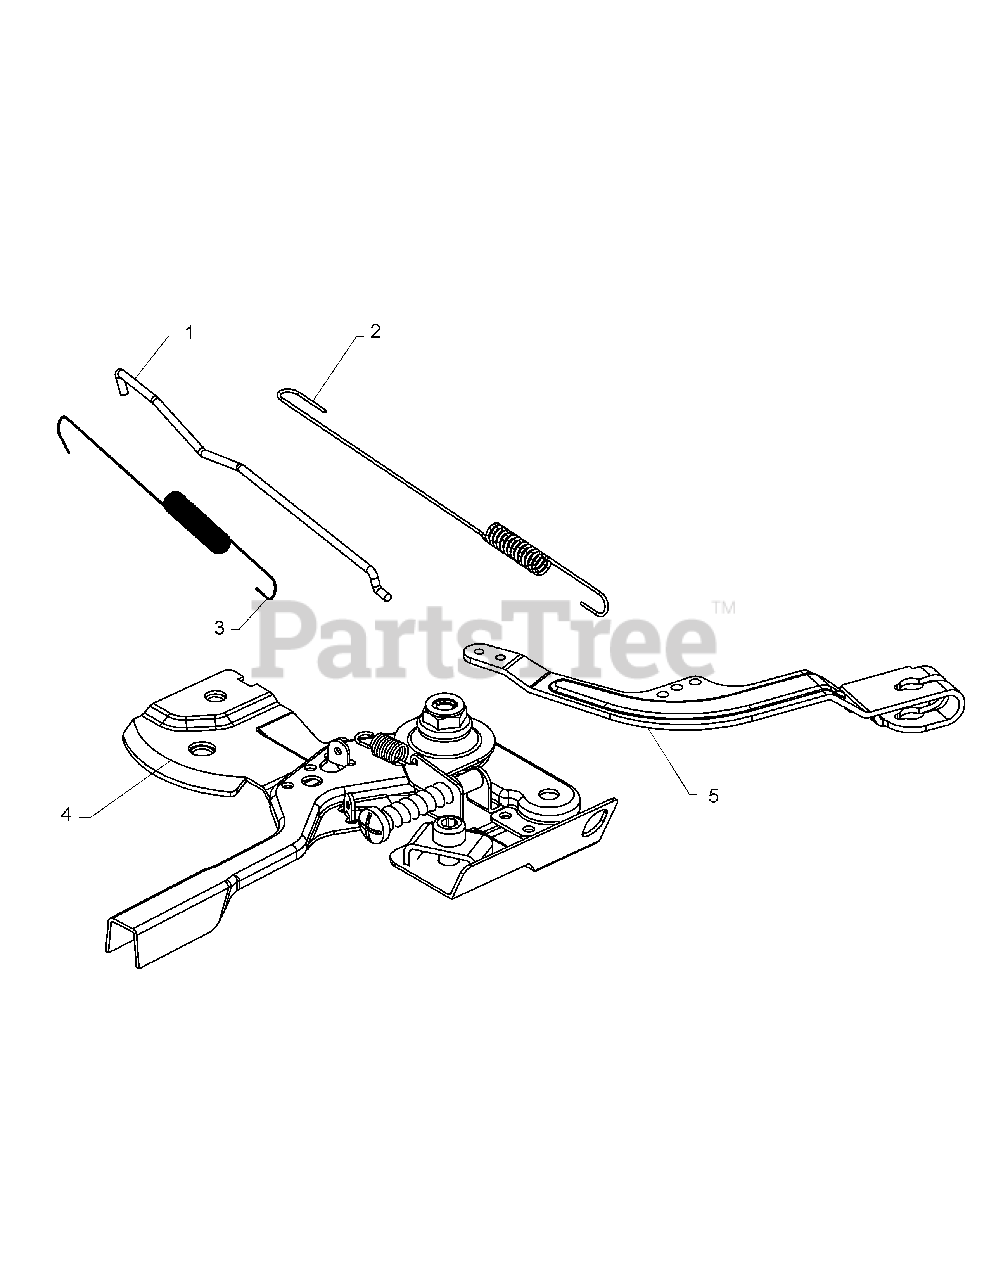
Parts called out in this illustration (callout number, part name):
1	Governor Linkage
2	Governor Spring
3	Linkage Spring
4	Variable Speed Control Assembly W/O Kill
5	Governor Lever Kit
